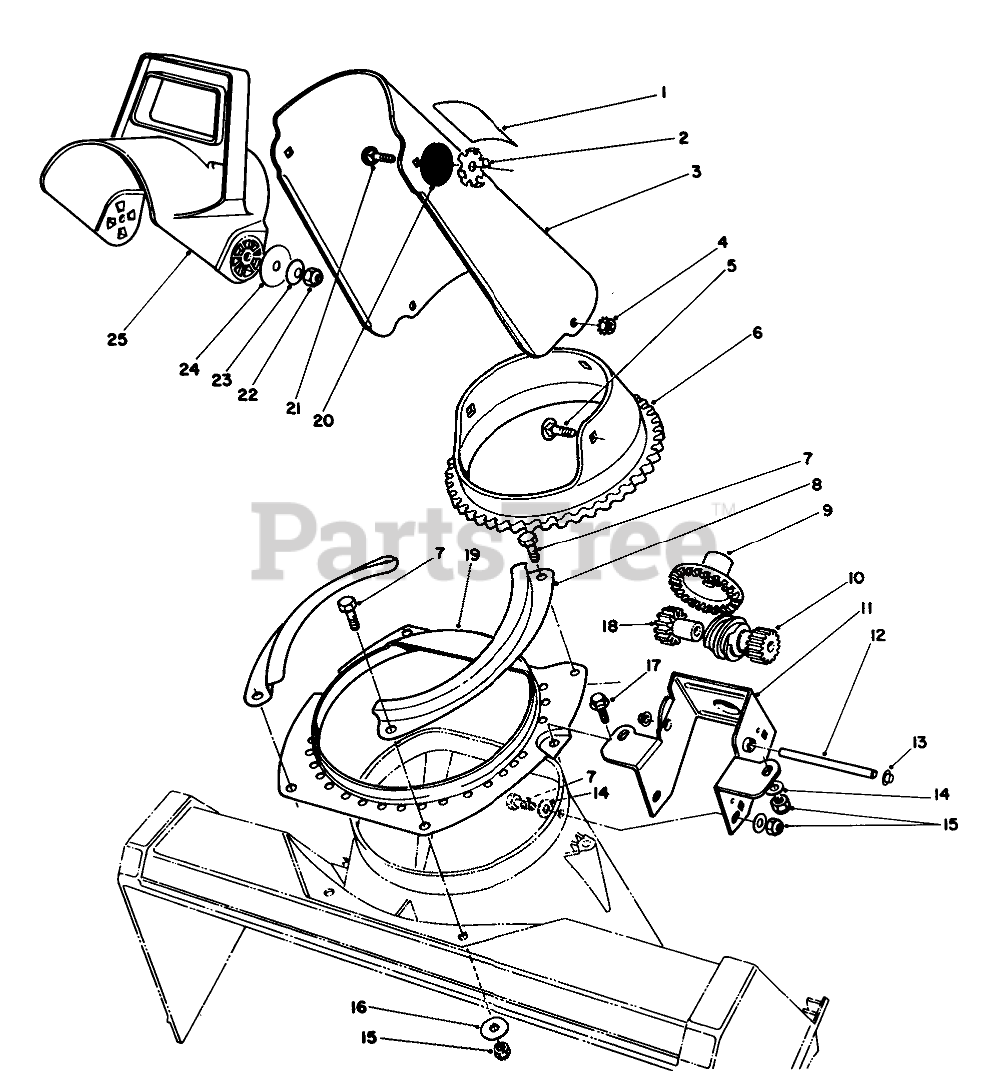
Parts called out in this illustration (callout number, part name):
1	Decal-Danger
2	PLATE-FRICTION
3	Chute-Discharge (Incl. Ref. #1:63-3760)
4	NUT-KEPS
5	SCREW-CARR
6	RING-GEAR, CHUTE
7	SCREW-HH
8	Retainer-Chute Ring
9	GEAR-FACE
10	GEAR-SPUR/WORM
11	Bracket-Chute Gear
12	SHAFT-GEAR, WORM
13	NUT-PUSH
14	WASHER-FLAT
15	NUT-LOCK, NI
16	WASHER-FLAT
17	SCREW-PLASTITE
18	GEAR-SPUR, SPACER
19	Ring-Chute Support
20	WASHER-RUBBER
21	SCREW-CARR
22	NUT-LOCK, NI
23	WASHER-BELLEVILLE
24	WASHER-FLAT
25	CHUTE-DEFLECTOR
